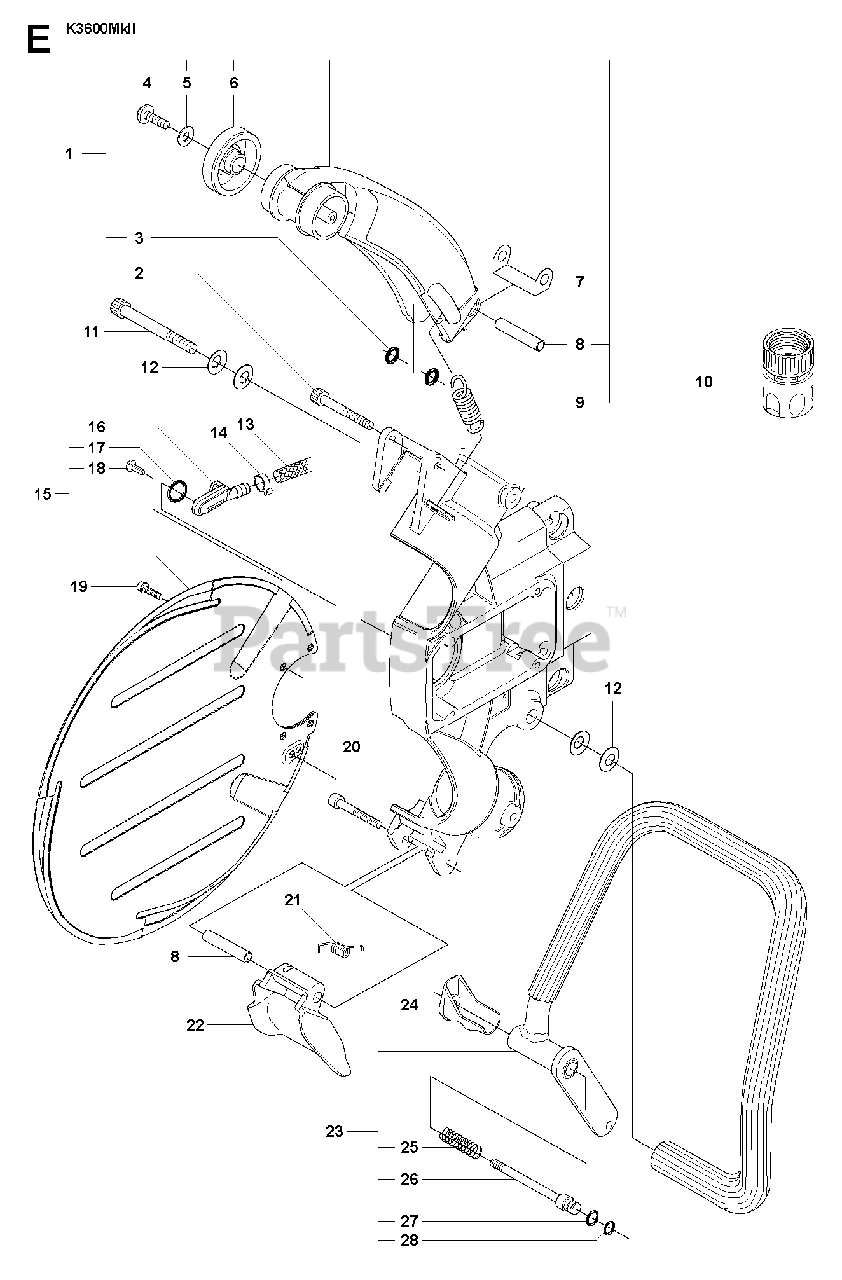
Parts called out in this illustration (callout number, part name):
1	BLADE GUARDIncl. 2, 3, 4, 5, 6, 7, 8, 9
8	SPACING TUBE
14	HOSE CLAMP
17	O-RING
18	SCREW CRPANT
23	HANDLE ASSYIncl. 24, 25, 26, 27, 28
